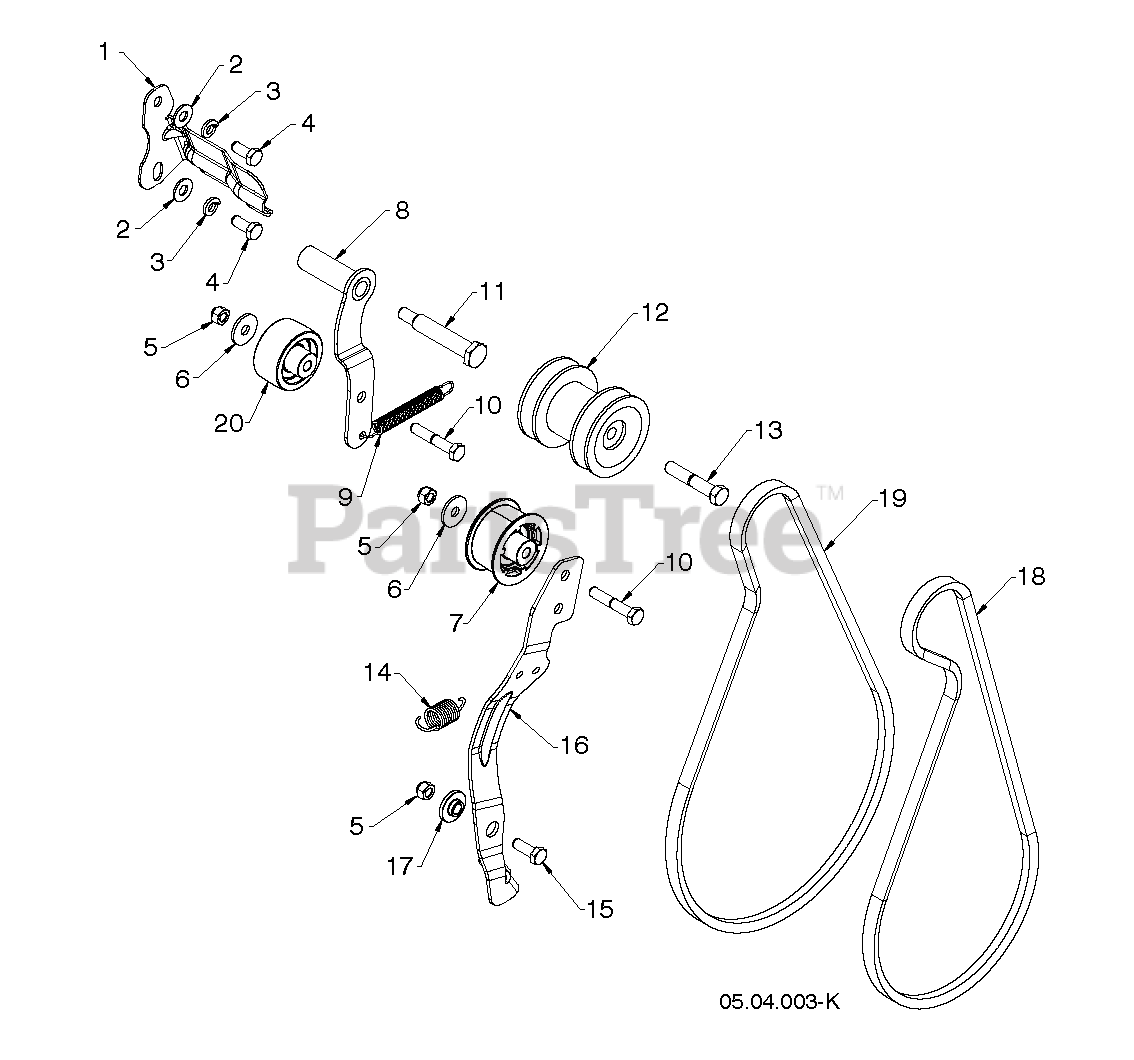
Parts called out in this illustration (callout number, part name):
1	BELT KEEPER BRACKET
2	WASHER M
3	WASHER.LOCK.HVY.HLCL.SPR.5/16
4	SCREW 5/16-24 X .75 GR5
5	NUT.71038.31-18.HEX.NYLOCK
6	STEEL WASHER
7	PULLEY,IDLER,2.00 W SPA
8	ARM IDLER DRIVE WELDMENT_HOT
9	SPRING RETURN IDLER ARM
10	BOLT, HEX 5/16-18X1-3/4
11	BOLT 5/16-24X2.25 HEX HEAD SHO
12	PULLEY.ASM.IMPELLER/DRIVE
13	BOLT.ENGINE.PULLEY
14	SPRING RETURN, IDLER ARM, IMPE
15	BOLT
16	ARM.IDLER.AUTO-PH.676
17	BUSHING.BRAKE.ARM
18	HIGH CRANK IMPELLER BELT
19	BELT.HIGH.CRANK.4LX41.RAW.EDGE
20	PULLEY.IDLER.FLANG.2.O/SPACER
